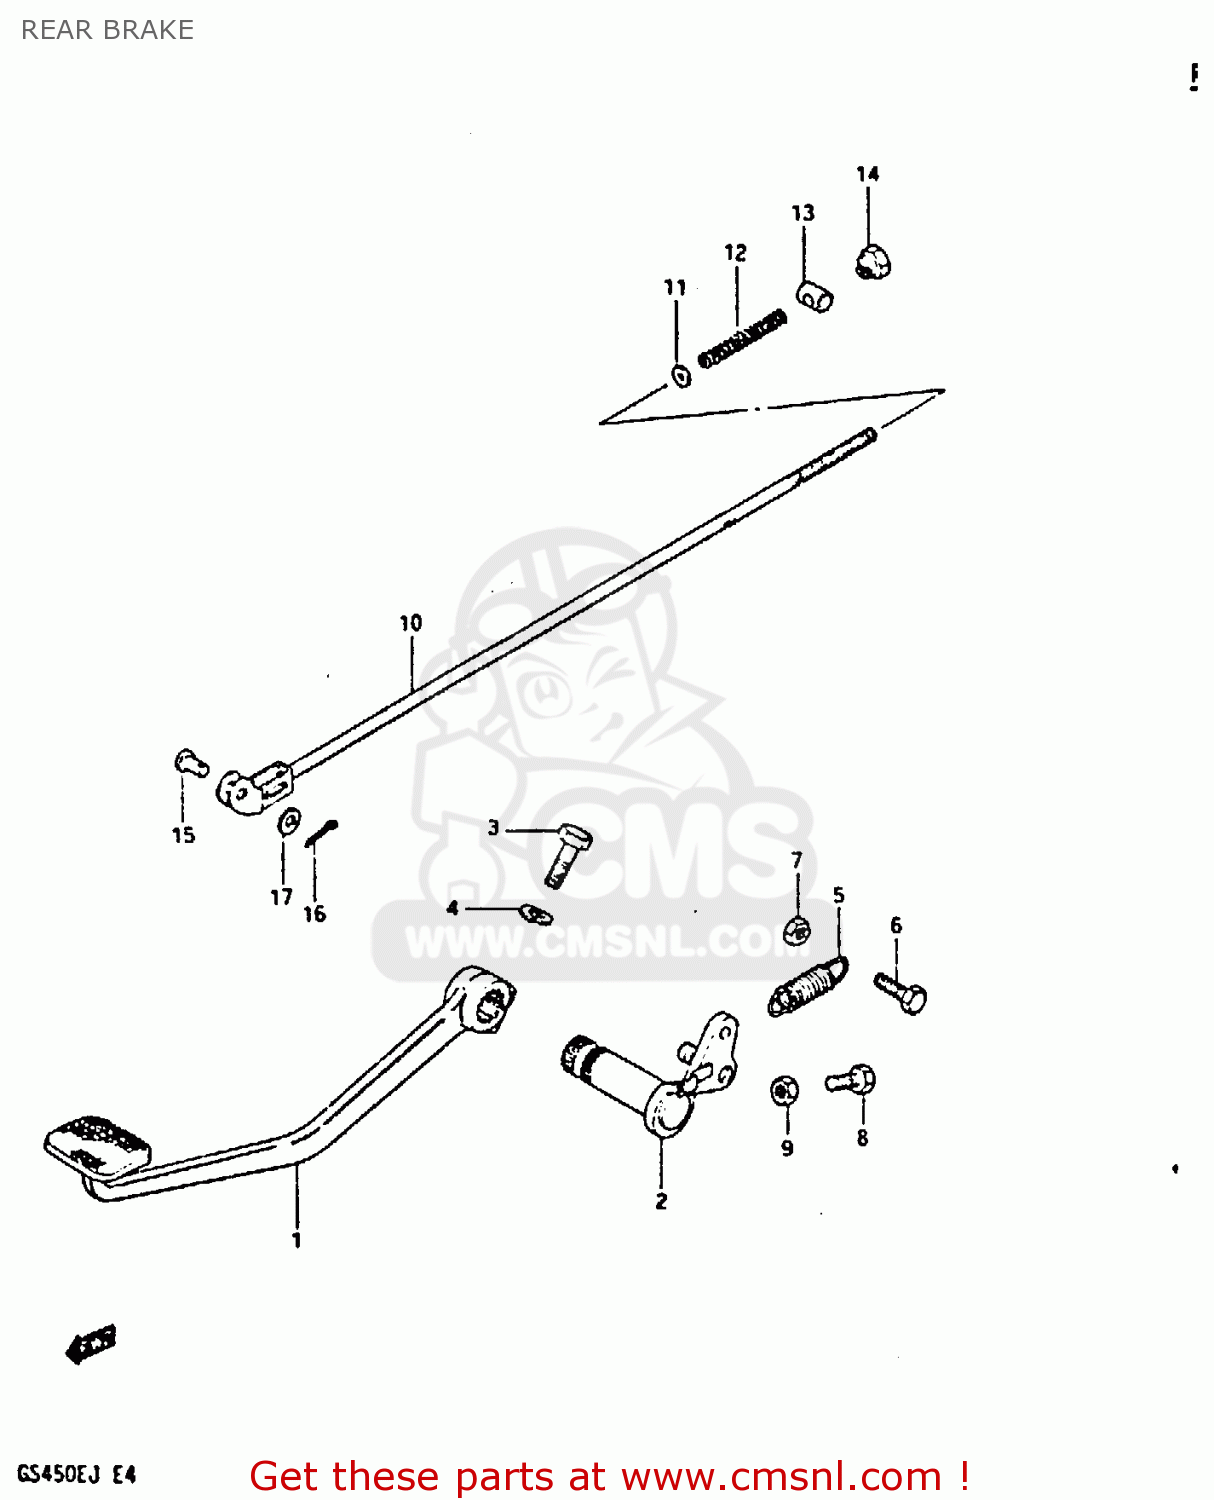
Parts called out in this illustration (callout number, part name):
1	PEDAL,BRAKE
2	ARM,BRAKE PEDAL
3	BOLT
4	LOCK WASHER
5	SPRING
6	BOLT
7	NUT 6MM
8	BOLT
9	NUT 6MM
10	ROD ASSY,RR BRAKE
11	WASHER
12	SPRING
13	PIN
14	NUT (6MM)
15	PIN(L:13.5)
16	PIN 20X20
17	WASHER
